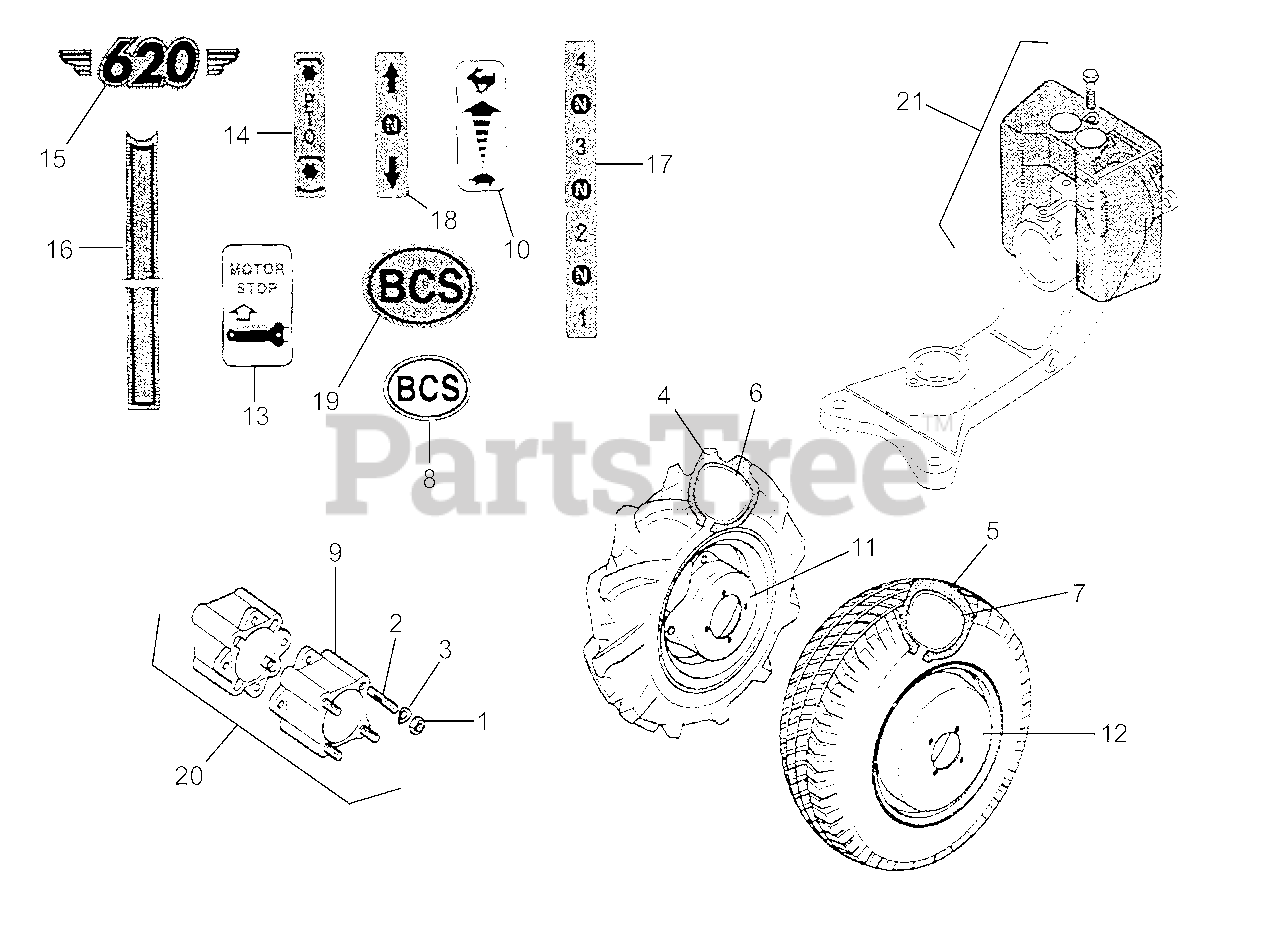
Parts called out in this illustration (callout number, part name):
1	NUT M 10 UNI 5588 6S
2	STUD M10X40X22X14 8G
3	SPRING WASHER B10,5 DIN 137
4	TIRE 4.00X10
5	TIRE 20X8.00-10
6	TUBE 4.00X10
7	TUBE 20X8.00-10
9	WHEEL EXTENSION
11	RIM 3.50 D 10" VAR.TREAD COMP
12	RIM 6.00 1-10"
20	WHEEL EXTENSION (PR)
21	WEIGHT/CUTTER BAR
